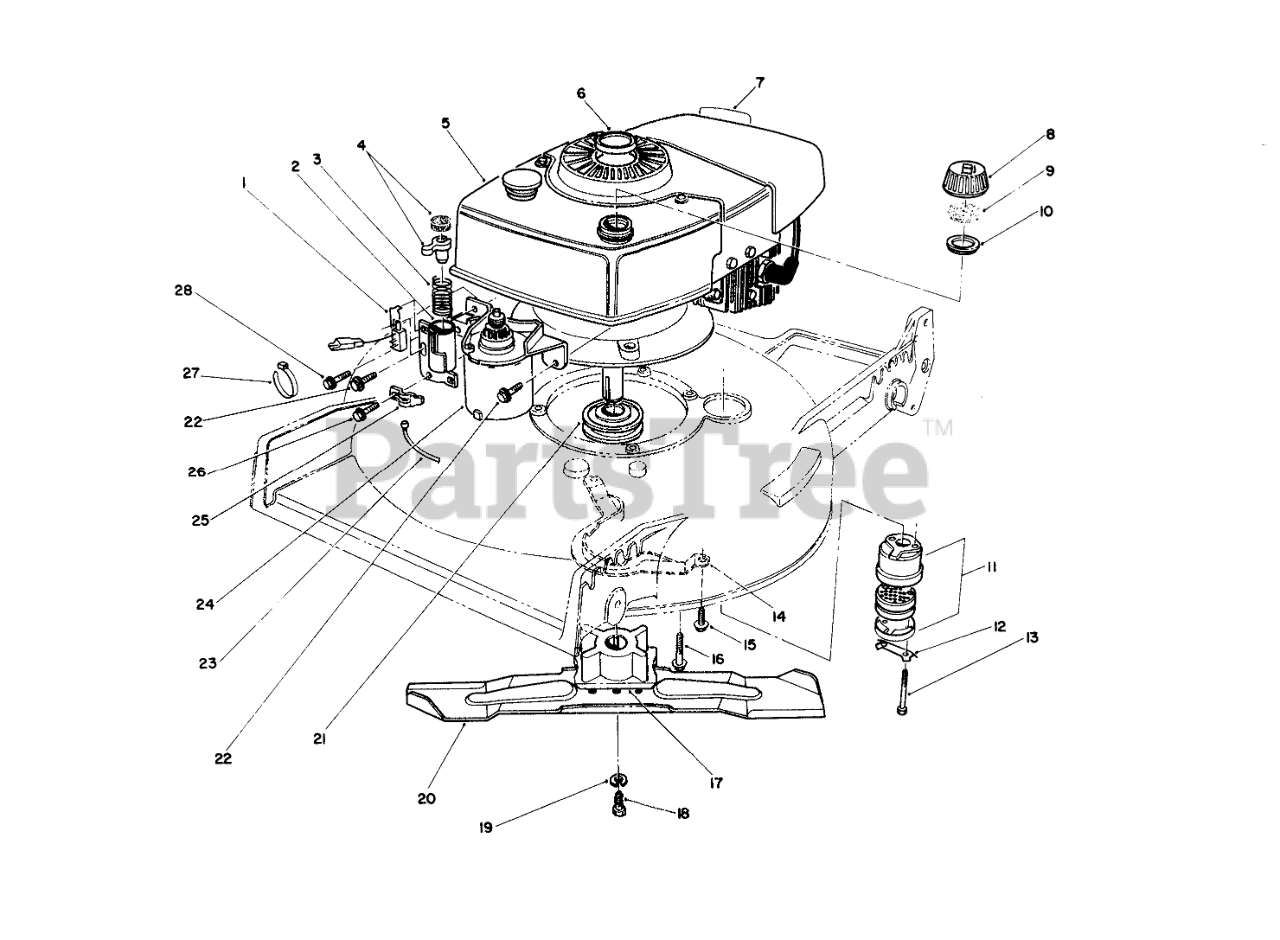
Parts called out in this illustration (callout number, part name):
1	PUSH BUTTON SWITCH
2	TUBE W A
3	COMPRESSION SPRING
4	BRAKE PAD/PLUNGER ASM
6	PLUG BUTTON
7	Decal-Maintenan
8	Gas Cap (Incl. Ref. #9 & 10)
9	GASKET
10	GAS CAP BAFFLE
11	Muffler Assembly (Incl. Ref. #12 & 13)
12	CLIP - LOCKING
13	SCREW-HH
14	BELT GUIDE
15	SCREW-HWHTF
16	3/8-16 X 2 CAPSCREW
17	BLADE RETAINER
18	SCREW-BLADE
19	WASHER-LOCK
20	BLADE-21in
21	PULLEY-DRIVE, ZONE START
22	SCREW
23	BRAKE CABLE
24	STARTER MOTOR ASM
25	CABLE CLAMP
26	SCREW
27	TIE-CABLE
28	Screw
